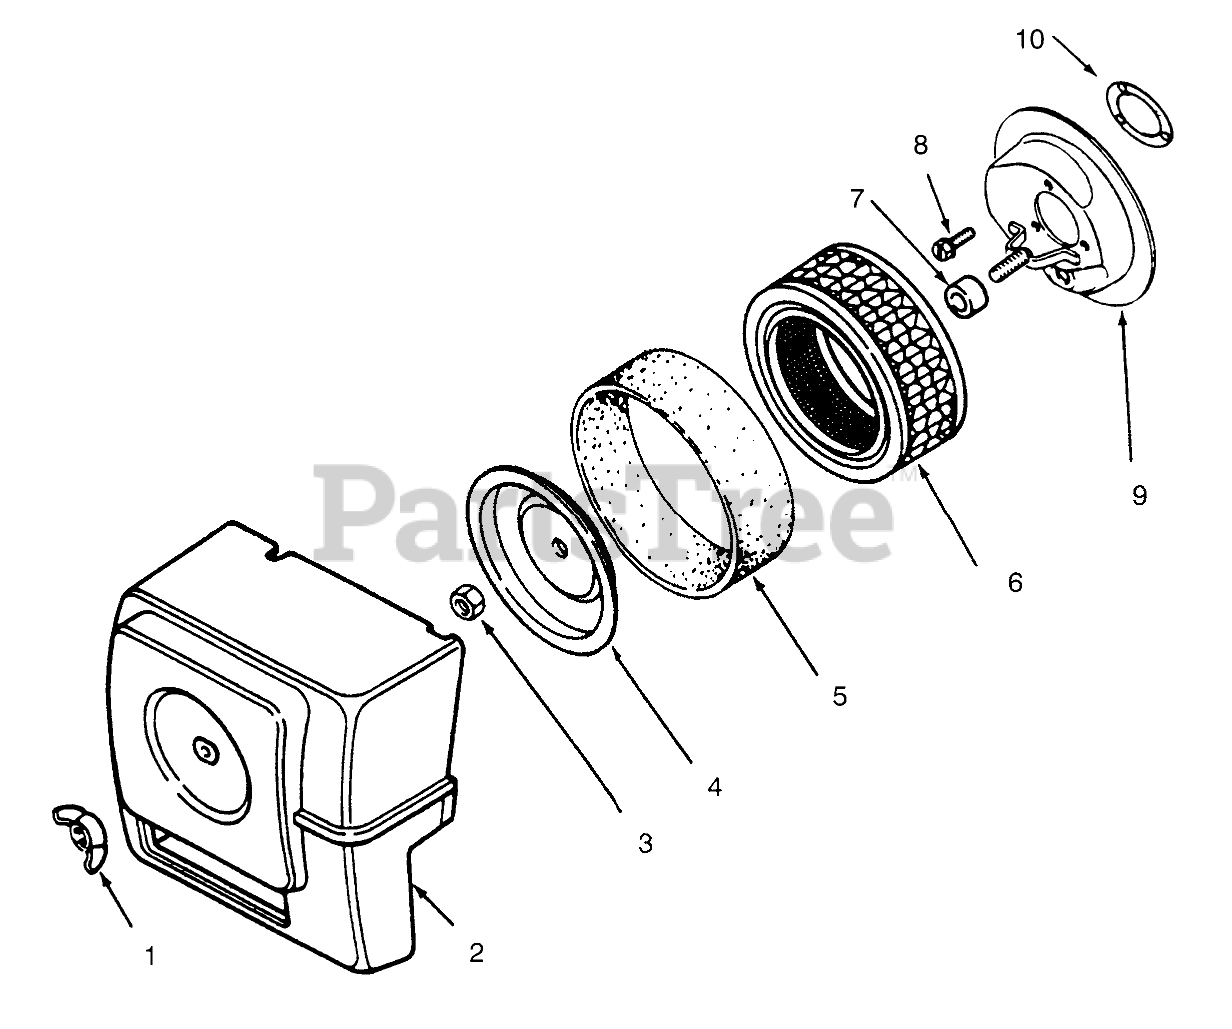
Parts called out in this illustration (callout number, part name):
1	Nut-Wing
2	Cover
4	Air Cleaner Element Cover
5	Element-Precleaner
6	Element
8	Screw
9	Base-AirCleaner
10	Gasket
